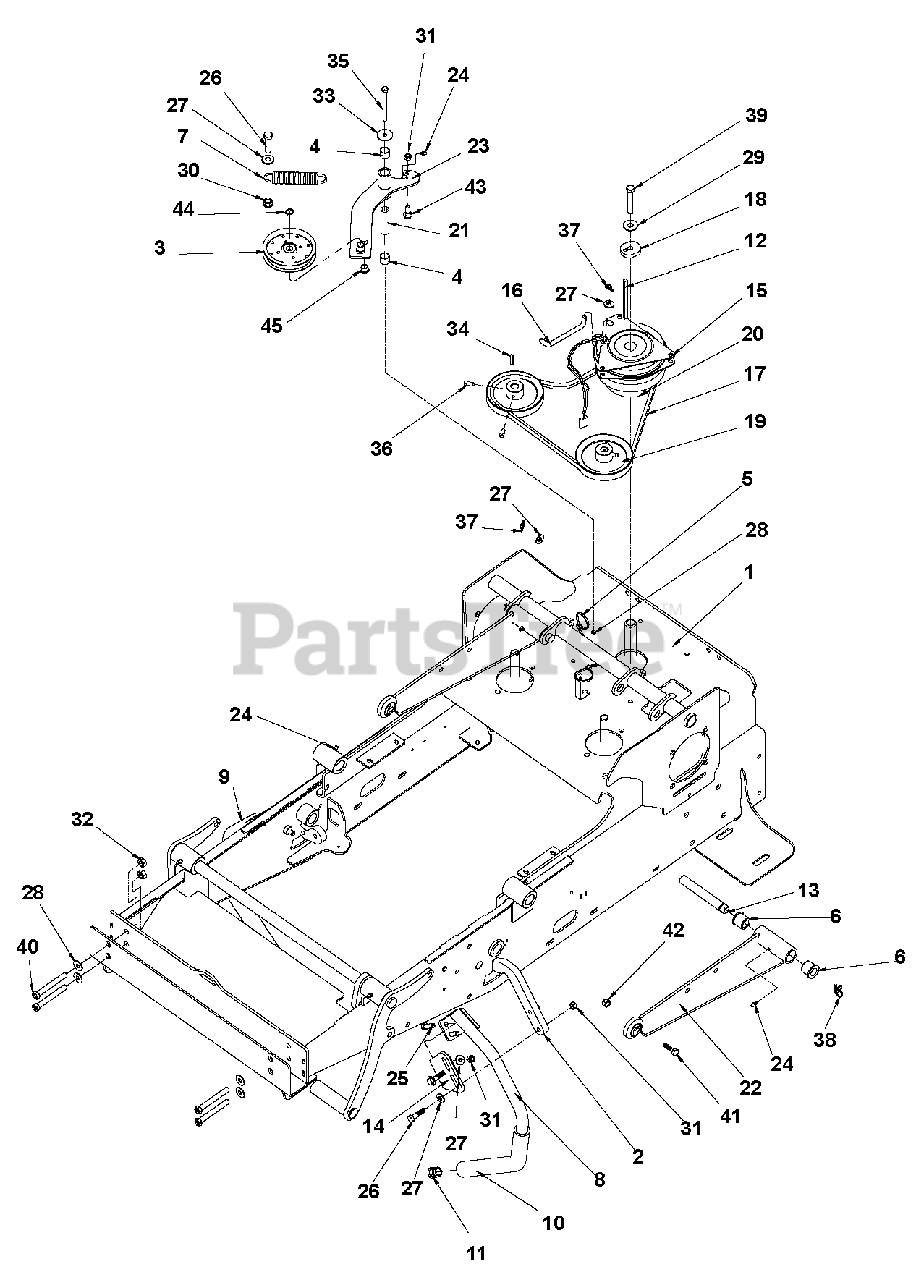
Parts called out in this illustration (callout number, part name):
1	Weldment, Frame and Deck Lift
2	Plate, Steering Control
3	Pulley, Flat 4.00 x .670 w/Bearing
4	Bearing, Sleeve .753 x .878 x .750
5	Cable Tie, .15 x 8.50
6	Bearing, Flange .750 x 1.13 x 1.00
7	Spring, Extension .875 x .125 x 4.25
8	Weldment, LH Steering Handle
9	Weldment, RH Steering Handle
10	Grip, Foam
11	Plug, 7/8" End
12	Key, .250 x .250 x 4.62 Square
13	Pin, MFG .625 x 5.38 x 4.88 x DRL
14	Plate, Steering Control Bent
15	Clutch, Electric - OGURA, GT2.5
16	Rod, Clutch Antirotation
17	Belt, A46K ARAMID CORD
18	Washer, Clutch Universal w/Key
19	Pulley, V-Belt 5.00 x .591 w/Key
20	Pulley, V-Belt 4.50 x 1.00 w/Key
21	Tube, Ø.750 x Ø.438 x 3.047
22	Weldment, Deck Push Link
23	Weldment, Pump Belt Tensioner
24	Fitting, 1/4-28 Straight Grease Zerk
25	Bolt, 3/8-16 X 1.25 Hex Grade 5
26	Bolt, 3/8-16 X 1.50 Hex Grade 5
27	Washer, .313 Reg Flat
28	Washer, .375 Reg Flat
29	Washer, .438 Reg Flat
30	Locknut, 3/8-16 Whiz
31	Locknut, 3/8-16 Crown
32	Locknut, 7/16-14 Crown
33	Washer, .375 X 1.50 X .O63 Flat
34	Key, M5 X M5 X M30 RD
35	Bolt, 3/8-16 X 4.00 Hex Grade 5
36	Set Screw, 5/16-18 X .625 Square Cup
37	Ring, Rue .375 x .054 x 1.254
38	Ring, Rue .750 x .080 x 2.081
39	Bolt, 7/16-20 X 2.75 Hex Grade 5
40	Bolt, 7/16-14 X 3.5 Hex Grade 5
41	Bolt, 1/2-13 X 2.25 Hex Grade 5
42	Locknut, 1/2-13 Crown
43	Bolt, 1/2 X 1.06 X 3/8-16 X .421
44	Snap Ring
45	Bearing, Flange .502 X .629 X .421
